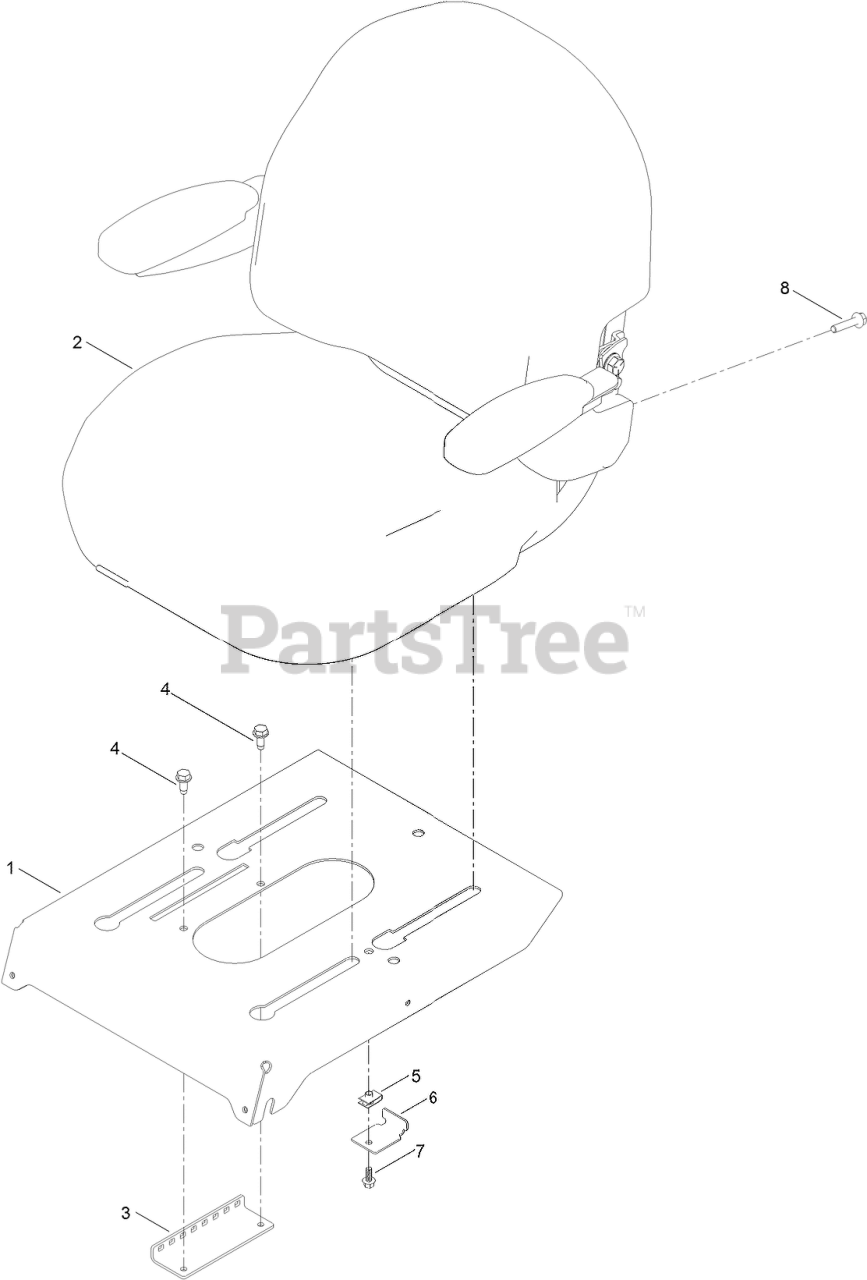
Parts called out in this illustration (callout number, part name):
1	PAN-SEAT
2	SEAT ASM
3	BRACKET-LATCH, SEAT
4	SCREW-HWHTF
6	BRACKET-STOP, SEAT
7	SCREW-HHF
8	SCREW-HHF
